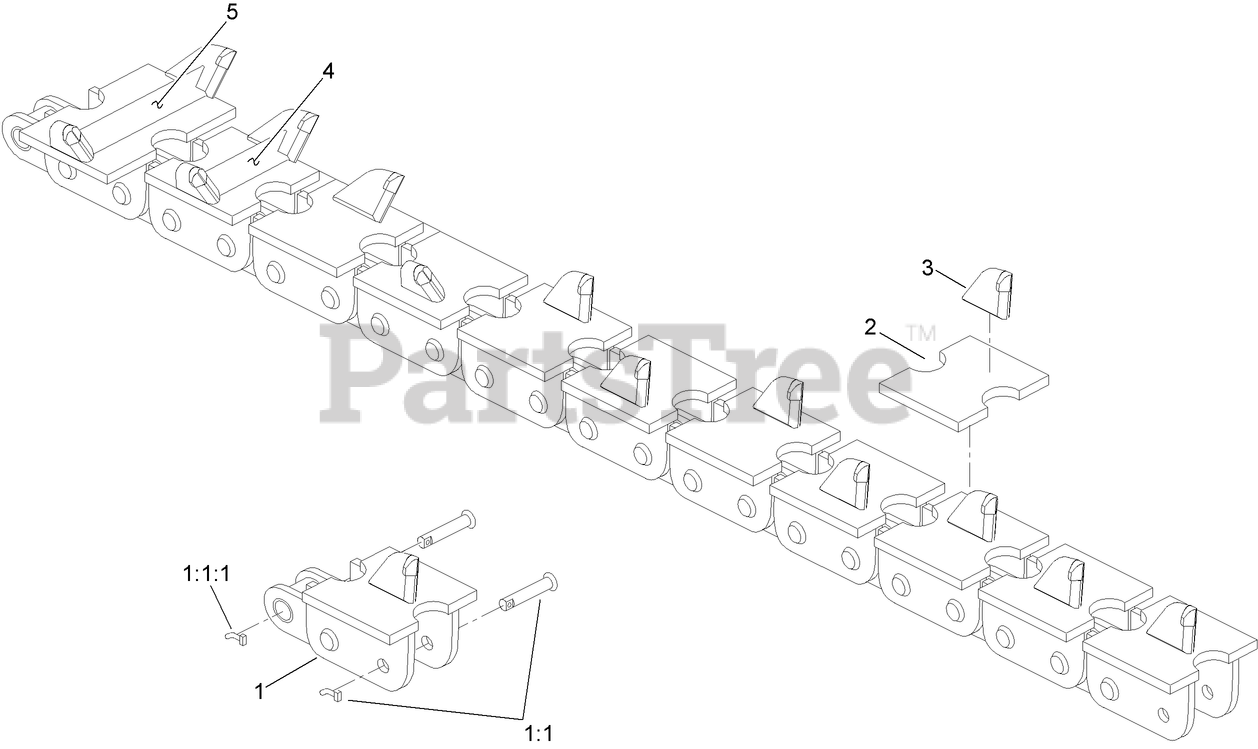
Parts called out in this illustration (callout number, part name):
1	CHAIN REPAIR LINK ASM
1:1	NOTCHED PIN AND KEEPER ASM
1:1:1	PIN-KEEPER
2	PLATE-H, WELD-ON
3	TOOTH-TERMINATOR, WELD-ON
4	DRAG-DIRT, WELD-ON
5	DRAG-DIRT, WELD-ON
